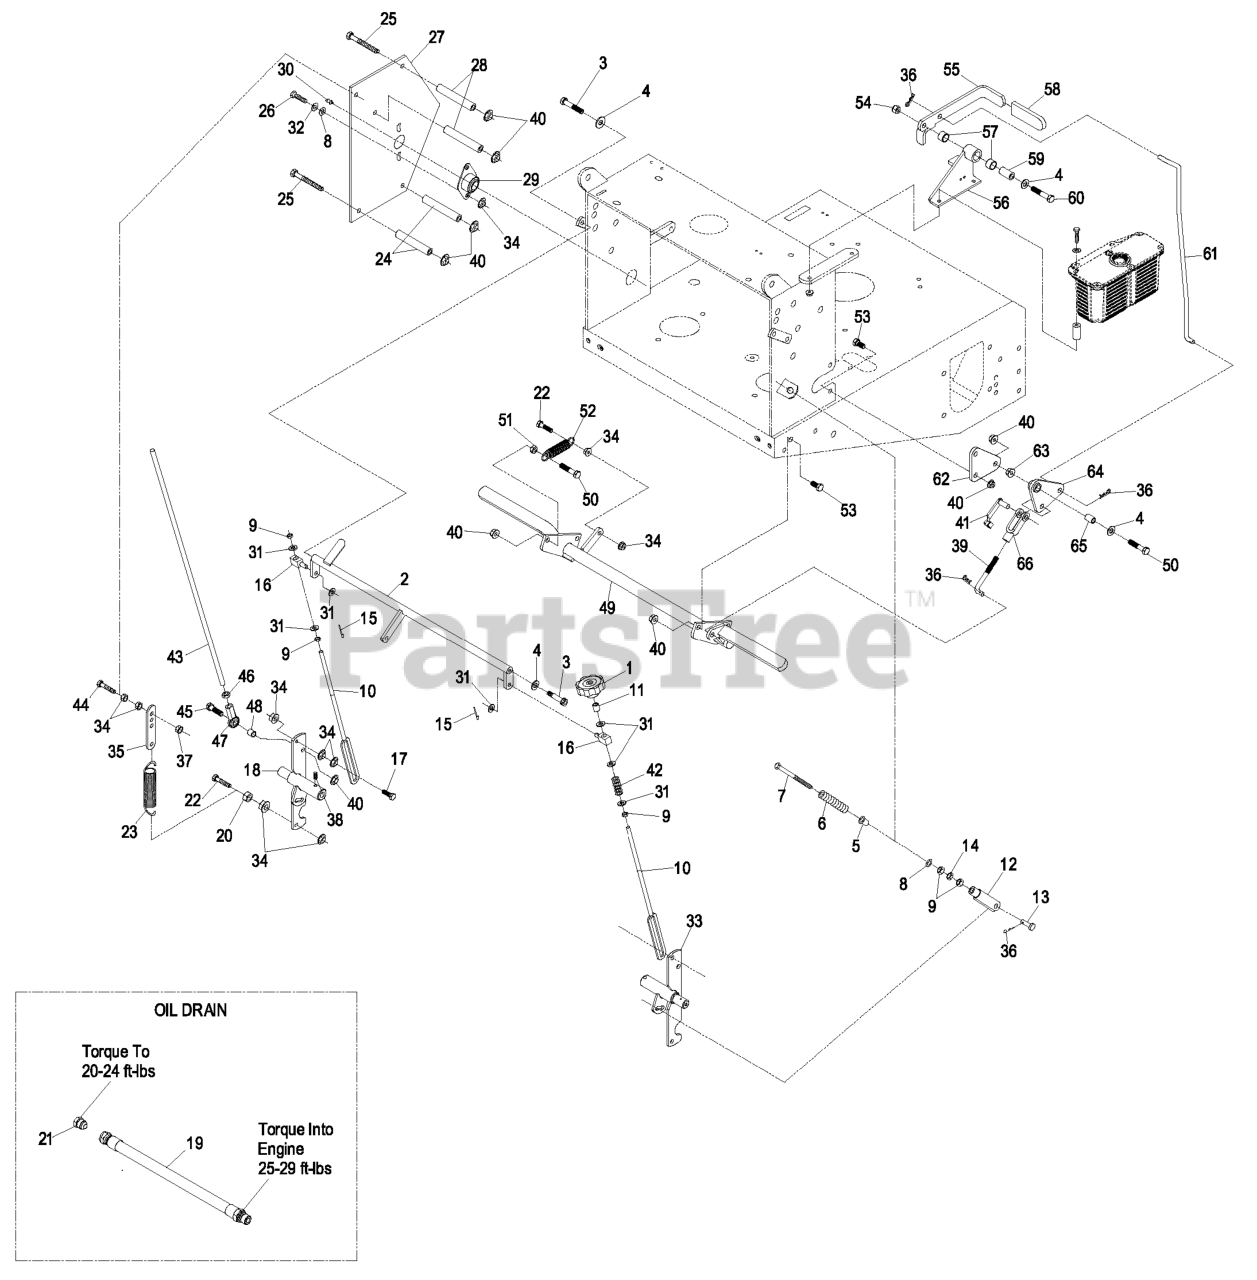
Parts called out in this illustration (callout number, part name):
1	KNOB-TRACKING
2	CRANK-CONTROL, SPEED
3	SCREW-HSH
4	WASHER-FLAT
5	BUSHING-FLANGED
6	SPRING,COMPRESSION (NEUT)
7	BOLT-RETURN, NEUTRAL
8	WASHER-FLAT
9	NUT-HEX
10	LINK-CONTROL, SPEED
12	YOKE-ADJUSTABLE
13	PIN-CLEVIS
14	NUT-JAM
15	PIN-COTTER
17	SCREW-HH
18	SHAFT-CONTROL, LH
20	NUT-JAM
22	SCREW-HH
23	SPRING-EXTENSION
24	SPACER-SHIELD
25	SCREW-HH
26	SCREW-HH
27	SHIELD-CONTROL
28	SPACER-SHIELD
29	BEARING-FLANGE, SIDE
30	FITTING-GREASE
31	WASHER-PLAIN
32	WASHER-LOCK
33	SHAFT-CONTROL, RH
35	TAB-SPRING, EXTENSION
36	PIN-COTTER
37	NUT-LOCK, NI
38	SCREW-SET
39	LINKAGE-LOWER
40	NUT-HHF, WHIZ
41	PIN-SPRING, CLEVIS
42	SPRING-COMPRESSION
43	LINKAGE,DRIVE (PLT)
44	BOLT-TAP, HH
45	SCREW-HH
46	NUT-HEX JAM, LH
47	JOINT-BALL END, LH
48	SPACER-TUBE, PUMP LINK
50	SCREW-HH
51	NUT-JAM
52	SPRING-IDLER
53	SCREW-HH
54	NUT-LOCK, NI
55	LEVER,PARK BRK W/DECAL
56	BRACKET ASM
57	SLEEVE-BUSHING
58	GRIP-LEVER
59	BUSHING-PIVOT
60	SCREW-HH
61	LINKAGE-UPPER
62	BELLCRANK
64	BELLCRANK ASM
65	BUSHING-PLASTIC
66	YOKE-LINKAGE, BRAKE
